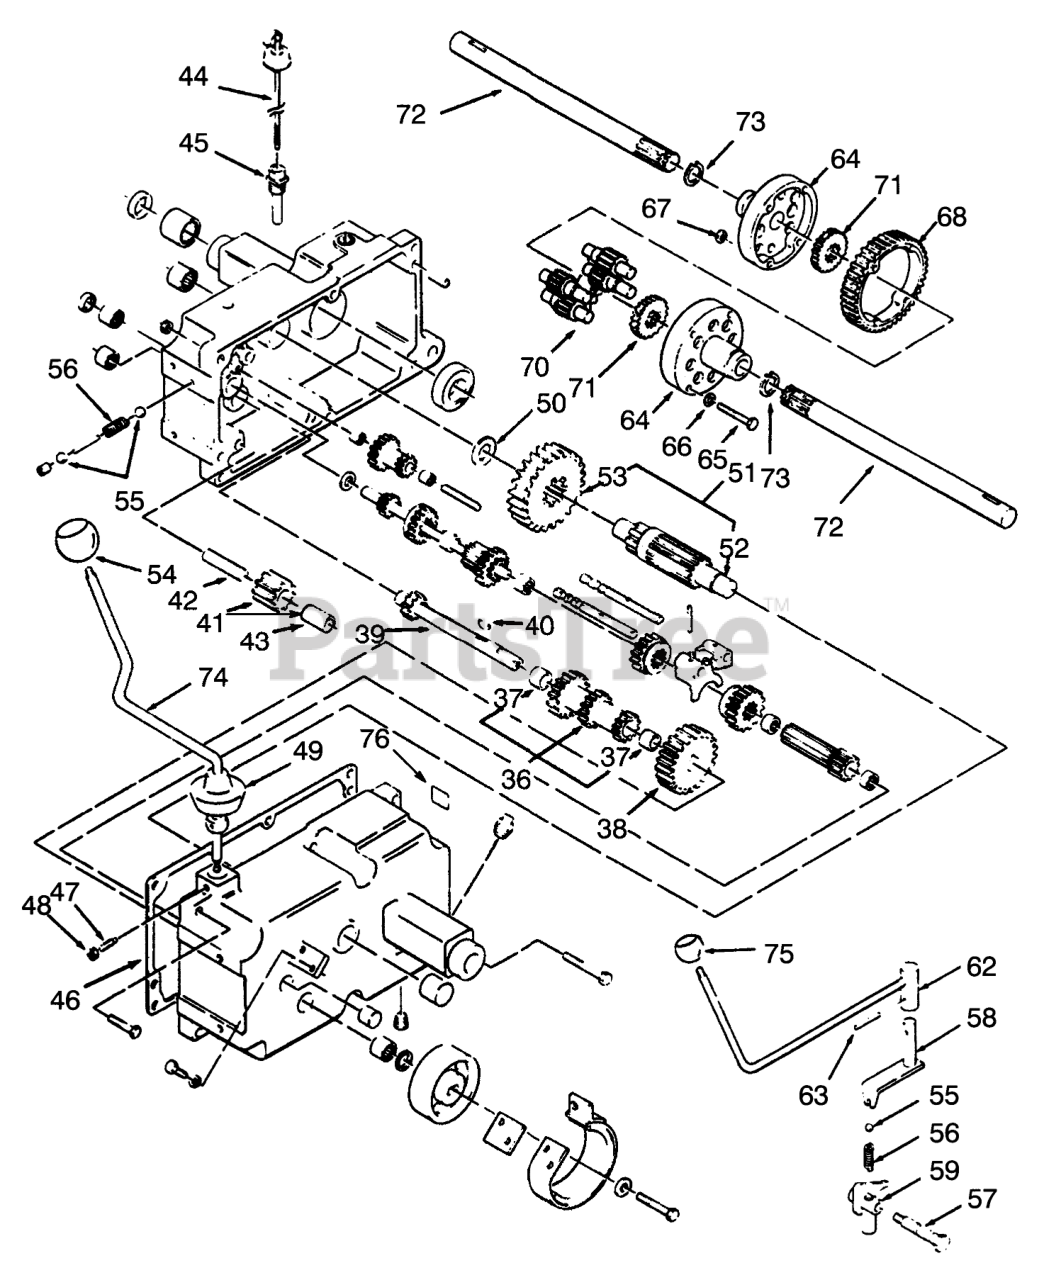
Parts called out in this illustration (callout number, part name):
36	Gear Assembly (Incl. Ref. #37)
37	BUSHING-BRONZE
38	GEAR-CLUSTER SHAFT
39	SHAFT-CLUSTER
40	KEY-WOODRUFF
41	Gear Assembly, Reverse Idler (Incl. Ref. #43)
42	PIN-DIFFERENTIAL
43	BUSHING
44	Dipstick
45	NIPPLE-FILL, TRANSMISSION
46	GASKET-TRANSMISSION
47	SETSCREW
48	NUT-HEX
49	COVER-DUST
50	WASHER-THRUST
51	Gear Assembly (Incl. Ref. #52 & 53)
52	PINION SHAFT
55	BALL-DETENT
56	SPRING-SHIFT STOP
57	BOLT-DETENT
58	SHIFT ASM
59	SHIFT FORK ASM
62	SHIFT ROD ASM
63	PIN-SPIROL
64	END CAP-DIFFERENTIAL
65	BOLT-HEX
66	WASHER
68	GEAR-DIFFERENTIAL RING, 43T
70	GEAR-PINION, 11T
71	GEAR-AXLE DIFFERENTIAL
72	AXLE-REAR
73	RING-SNAP
74	ASM-Rod
76	Decal-Unidrive
